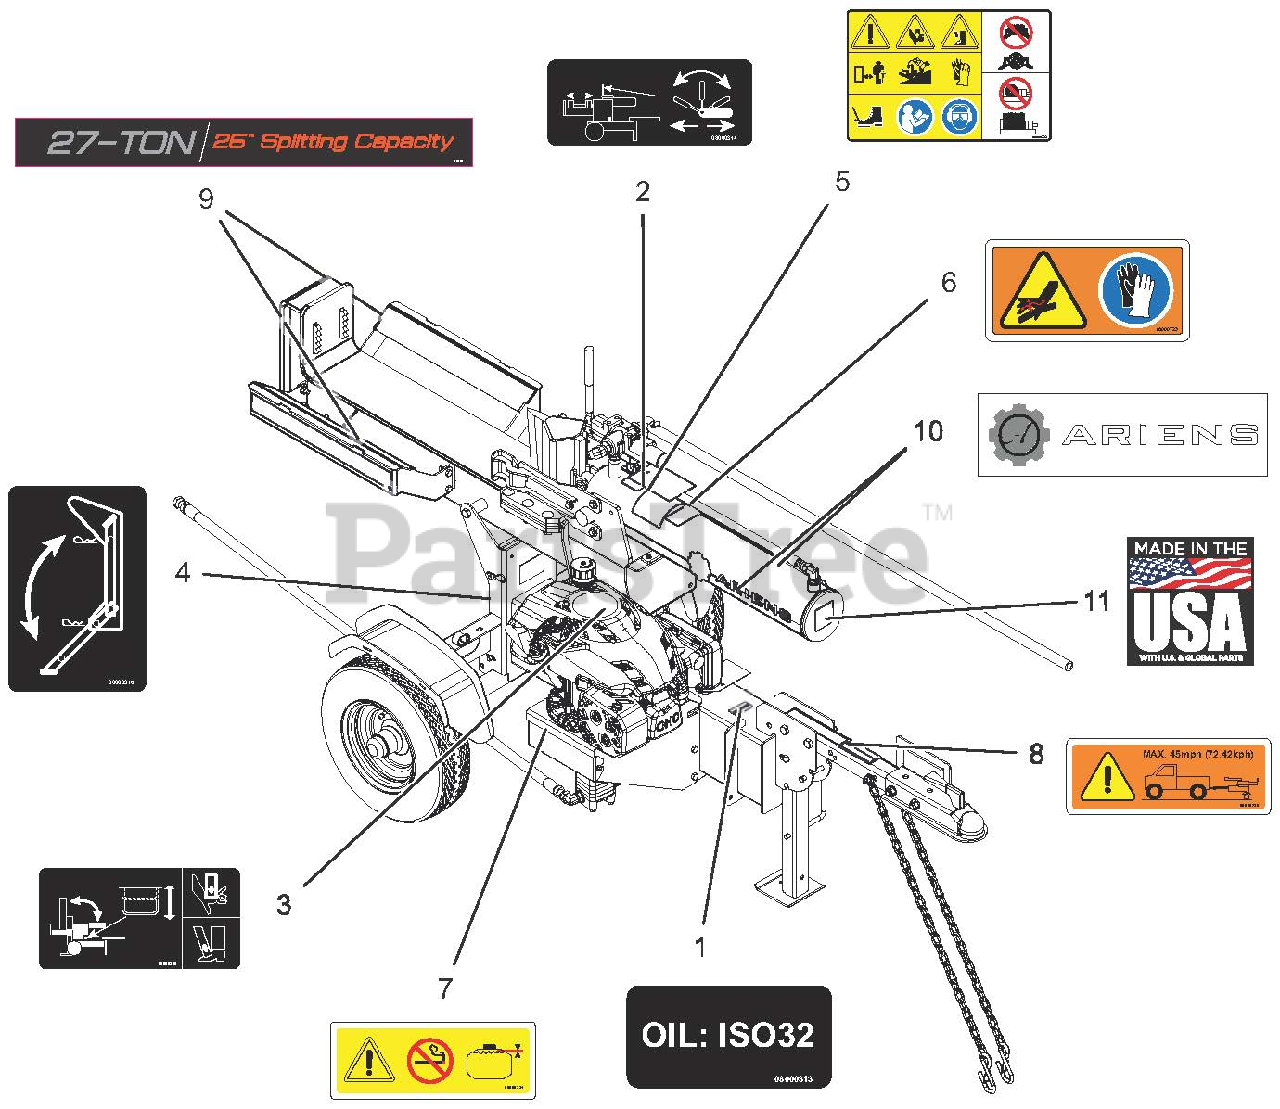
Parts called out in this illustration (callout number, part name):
1	DECAL, LOG SPLITTER-HYD OIL
2	DECAL, LOG SPLITTER-RAM OP
3	DECAL, LOG SPLITTER-TILT OP
4	DECAL, LOG SPLITTER-REAR STAND
5	DECAL,DANGER LOG SPLITTER
6	DECAL,HYD WARNING
7	DECAL,FUEL WARNING
8	DECAL,TOWING
9	DECAL-CRADLE-27 TON
10	DECAL-ARIENS-CYLINDER
11	DECAL, MADE IN USA
